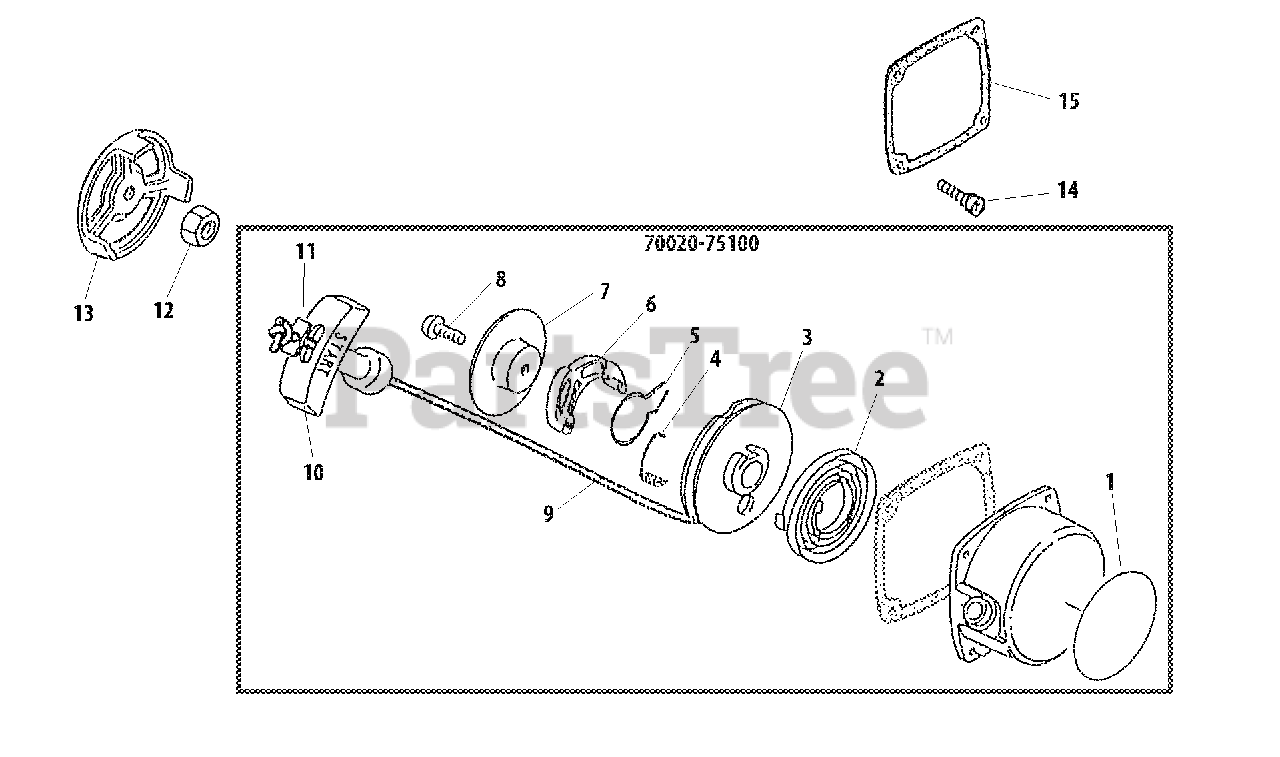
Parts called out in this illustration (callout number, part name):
1	LABEL - MODEL
2	SPRING, REWIND
3	REEL, ROPE
4	SPRING, RETURN
5	SPRING
6	PAWL, STARTER
7	PLATE, STARTER
8	SCREW
9	ROPE
10	GRIP, STARTER
11	RETAINER, ROPE
12	NUT - 8
13	CATCHER, STARTER
14	SCREW - 4X16
15	GASKET
70020-75100	STARTER ASSY
